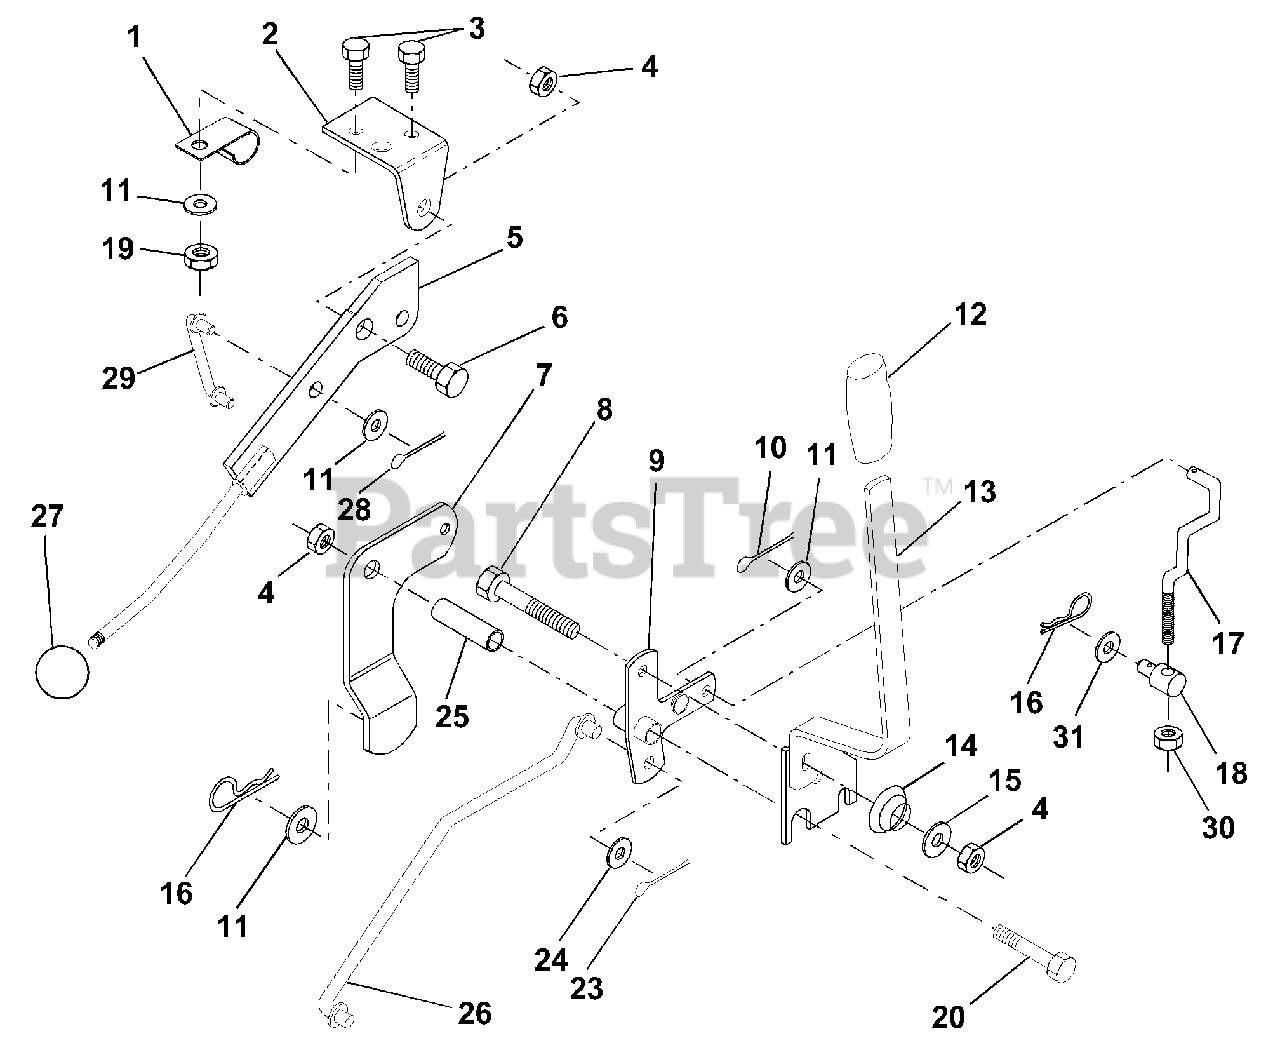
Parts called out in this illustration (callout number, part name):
1	Clip, Insulated
2	Bracket, Mower Clutch
3	Bolt, Fin. Hex 1/4-20 UNC x 1/2
4	Nut, Crownlock 3/8-16 UNC
5	Assembly, Clutch Lever
6	Bolt, Shoulder
7	Assembly, Mower Clutch Arm
8	Bolt, Hex 3/8-16 UNC x 2-1/4
9	Bellcrank, Asm. Lift
10	Pin, Cotter 1/8 x 3/4
11	Washer 13/32 x 13/16 x 16 Ga.
12	Grip, Handle
13	Assembly, Lift Handle
14	Spring, Compression
15	Washer 13/32 x 3/4 x 12 Ga.
16	Retainer, Spring
17	Link, Front Lift
18	Trunnion, Adj. 94
19	Nut, Crownlock 1/4-20
20	Bolt, Fin. Hex 3/8-16 UNC x 2-3/4
23	Pin, Cotter 1/8 x 1
24	Washer 17/32 x 1 x 16 Ga.
25	Tube, Spacer
26	Rod, Mower Lift
28	Pin, Cotter 3/32 x 3/4
29	Link, Mower Clutch
30	Nut Hex Jam 3/8-16 Unc
31	Washer 13/32 x 1-1/4 x 12
